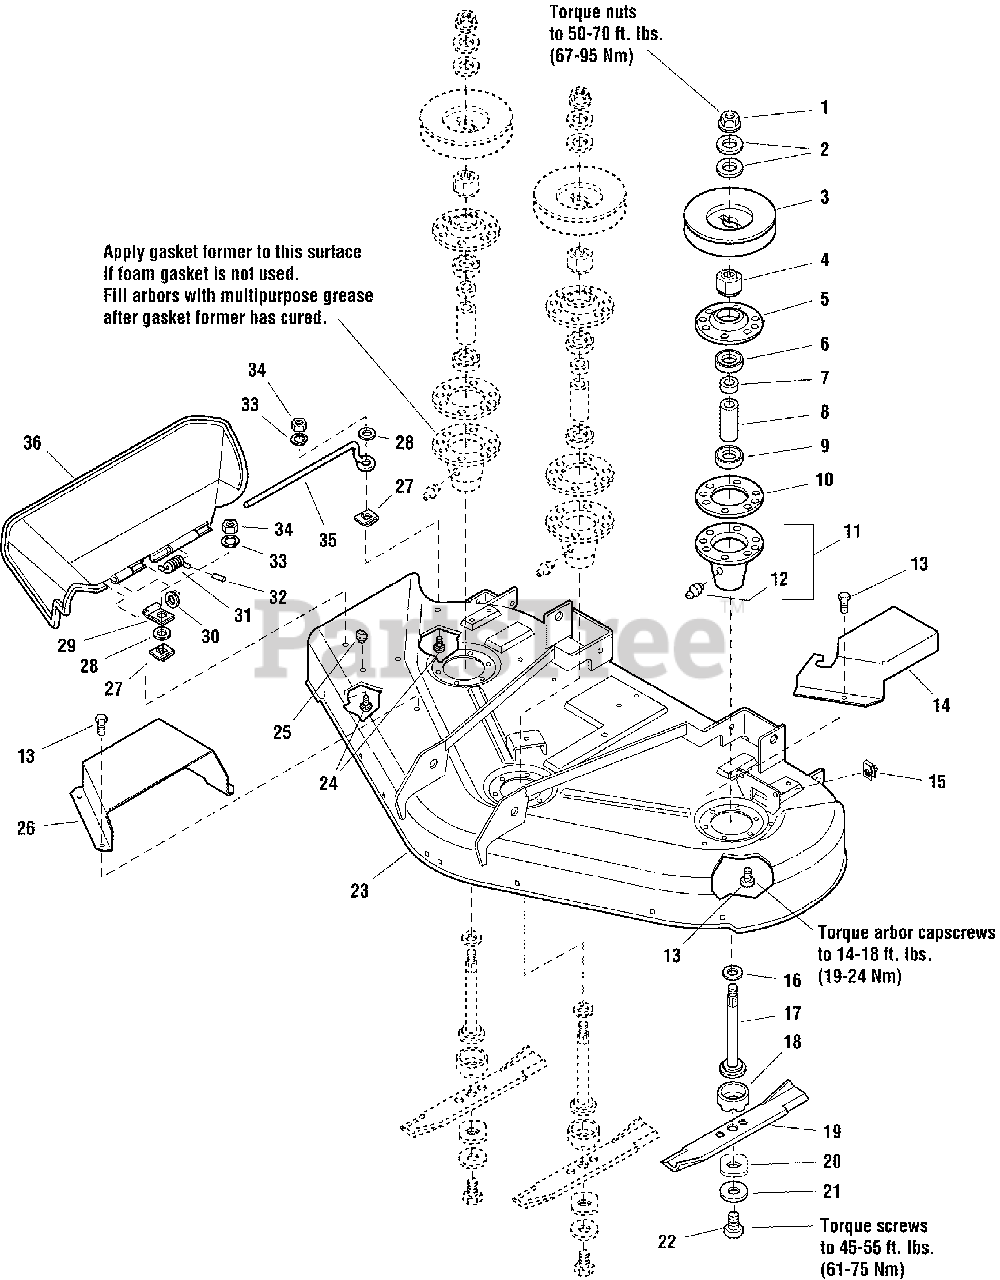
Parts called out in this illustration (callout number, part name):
1	NUT, HEX FLANGE, 9/16-18
2	WASHER, BELLEVILLED, 9/16
5	COVER, ARBOR HOUSING
6	BEARING, BALL, 3/4 X 1-3/4 X 5/8
7	SPACER, 21/32 X 3/4 X 5/8
8	SPACER, 11/16 X 5/32 X 2-11/16
9	BEARING, BALL, 11/16 X 1-9/16 X 15/32
11	ARBOR HOUSING ASSEMBLY
12	FITTING, GREASE
13	BOLT TAPTITE, 5/16-18 X 3/4
14	COVER, ARBOR, LH
15	BODY CLIP, 5/16-18
16	WASHER, 9/16, BLACK
17	SHAFT, ARBOR
18	SHIELD, GRASS, LOWER
19	BLADE, Mower, 16-1/8
19	BLADE, MOWER, 18-1/8
20	WASHER, HEX, 11/16 X 2
21	WASHER, SPRING, 15/32, BLACK
22	BOLT, 7/16-14 X 1-1/4
23	MOWER HOUSING ASSEMBLY, 44" MOWER
23	MOWER HOUSING ASSEMBLY, 50" MOWER
24	CARRIAGE BOLT, 1/4-20 X 7/8
26	COVER, ARBOR, RH
27	NUT, PUSH
28	WASHER, 1/4, BLACK
30	WASHER, 5/16, BLACK
33	WASHER, LOCK, 1/4
34	NUT, HEX, 1/4-20
35	ROD, DEFLECTOR
36	DEFLECTOR, PLASTIC
